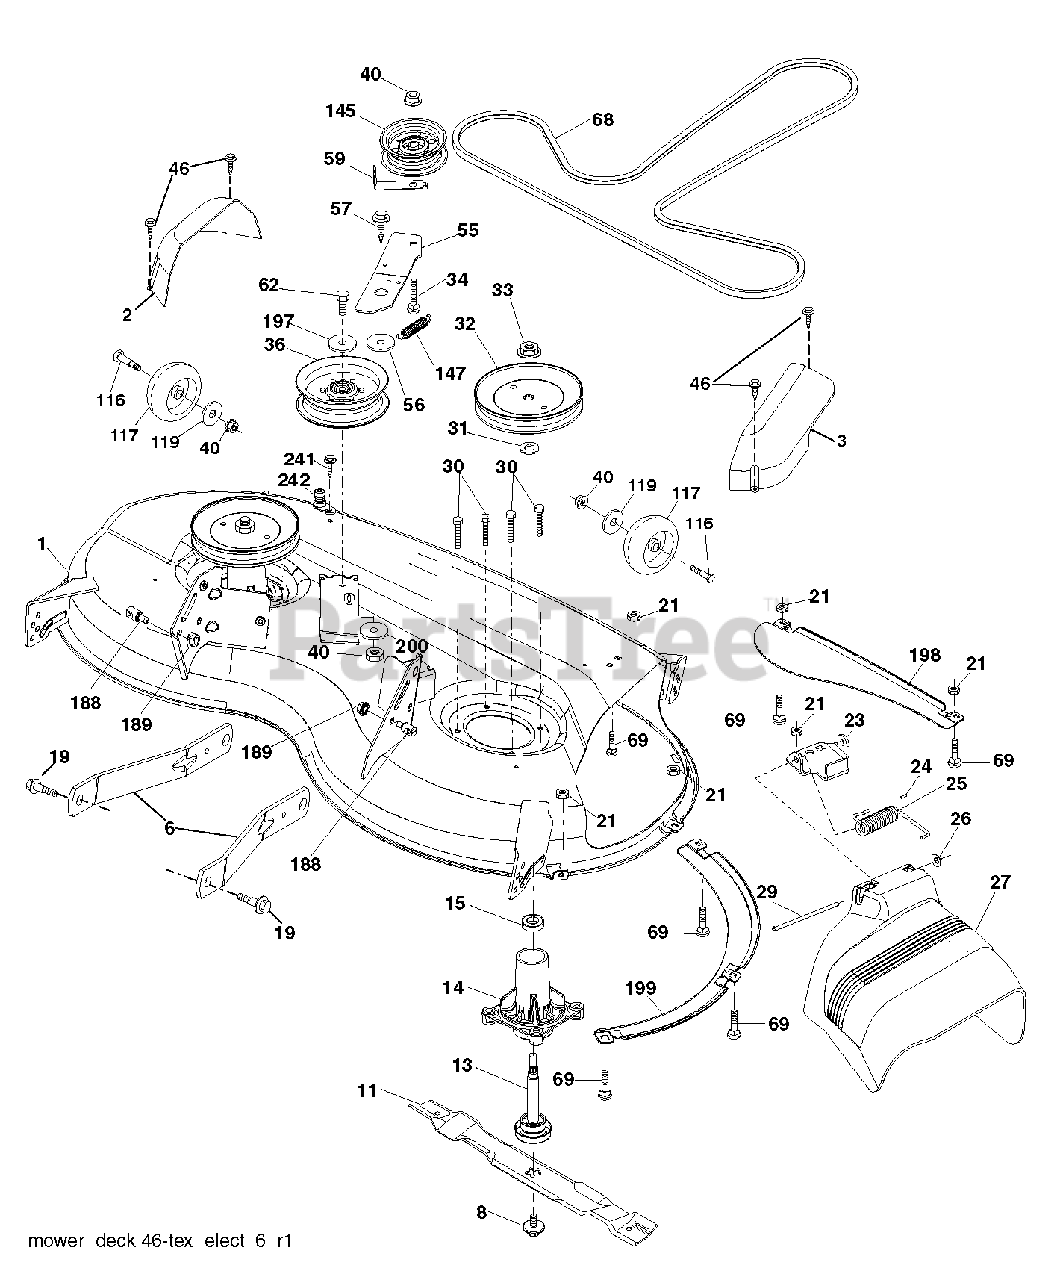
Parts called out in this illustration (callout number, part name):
1	DECK.WELDMENT.46"4GW.WHL.MS666
2	COVER MANDREL LH
3	COVER MANDREL RH
6	ARM.SUSPENSION.MOWER.R
8	BOLT.WASHER.ASM.7/16-2
11	BLADE 46" HI LIFT
13	SHAFT.ASM.MDRL.N/GREASE.38
14	HOUSING MANDREL
15	BEARING
19	BOLT.SHOULDER
23	BRKT.DEFLECTOR.38"2005
24	CAP-SLEEVE LT
25	SPRING.TORSION.DEFLECT
26	NUT PUSH M
27	SHIELD, DEFLECTOR
29	HINGE ROD
30	SCREW, WASHER HEAD
33	NUT.FLANGE.LOCK.TOP
46	SCREW 1/4-20X5/8
55	IDLER.ARM
56	SPACER.RETAINER
57	SCREW 3/8-16X1
59	GUARD
62	BOLT-HEX EAK
68	V BELT
69	BOLT
116	BOLT M
117	WHEEL GAGE.HALF.SPOKED
145	PULLEY.IDLER.48"PRIMARY
147	SPRING.MOWER.DRIVE.ELECTRIC
188	STUD.FASTNER.W/D.ANTI-
189	NUT LOCK HEX FLANGE 5/16-18
198	BAFFLE CENTER FRONT
199	BAFFLE FRONT RH
200	WASHER.13/32 X 1 X 1/2.11GUARD
242	PORT.WASHOUT
